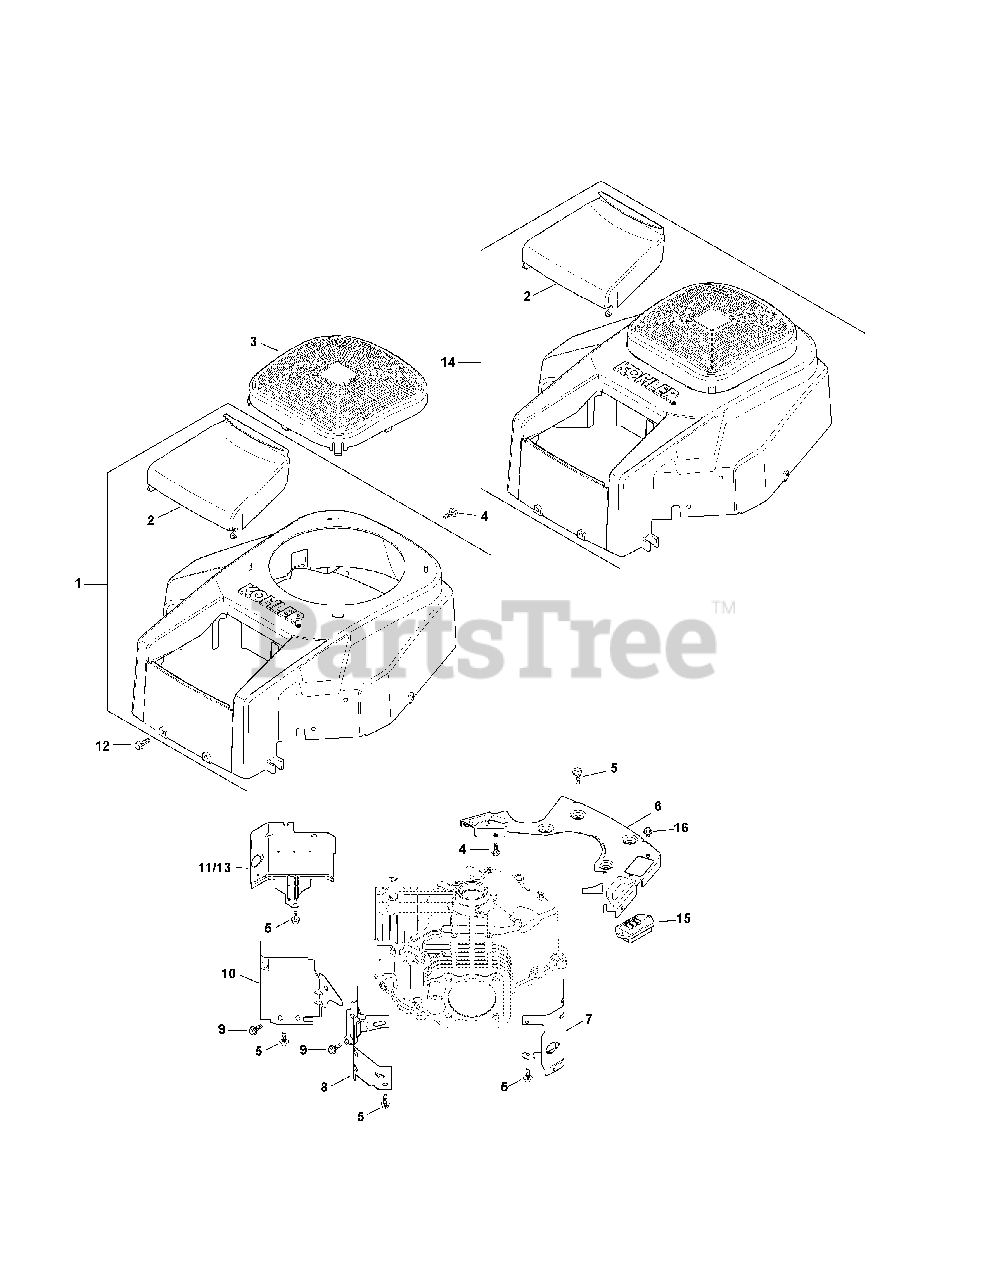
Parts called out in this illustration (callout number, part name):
1	Housing Blower Kit (Inc. 2 & KH-41-037-10-S)
2	Air Cleaner Cover
3	Not used in this application
4	Flg. Thd. Frm. Screw, M5 X 0.8 X 16
5	Flg. Thd. Frm. Screw, M6 X 1.0 X 16
6	Backing Plate Kit
7	Cyl. Barrel Baffle - #2 Side
8	Valley Baffle - #2 Side
9	Flg. Thd. Frm. Screw, M5 X .8 X 10
10	Valley Baffle - #1 Side
11	Cyl. Barrel Baffle - #1 Side
12	Tap Screw, M6 X 1.7 X 18
14	Not used in this application
15	Regulator/Rectifier
16	Flg. Thd. Frm. Screw, M6 X 1.0 X 10
